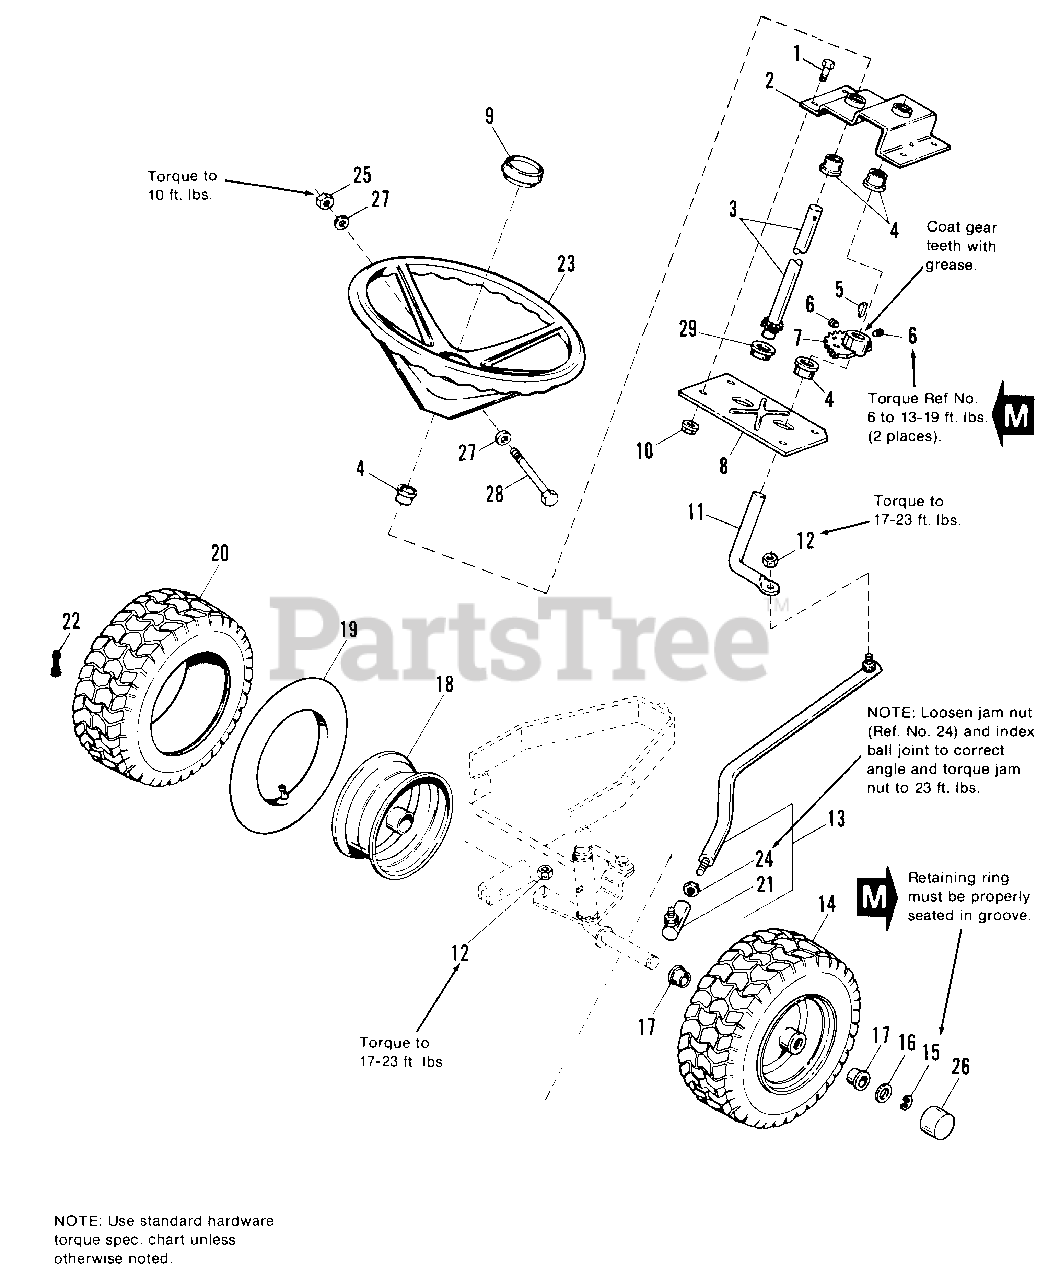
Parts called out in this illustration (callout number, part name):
1	CAPSCREW, Hex Hd., 5/16-18 x 3/4
2	PLATE, Steering
3	SHAFT ASSY., Steering
4	BUSHING, Nylon, Long
6	SETSCREW, 5/16-18 x 1/2
7	GEAR, Steering
8	PLATE, Base, Steering
9	CAP, Steering Wheel
10	LOCKNUT, Hex, Flange, 5/16-18
11	ROD, Steering
12	NUT, Special, 3/8-24
13	LINK ASSY., Drag (Incl. Ref. No. 21 & 24)
14	WHEEL & TIRE ASSY.
18	WHEEL ASSY. 15 x 6.00-6 (Incl. Ref. No. 17)
19	TUBE, 4.10/3.50-6 (For Service Only)
20	TIRE, (Carlisle) 15 x 6.00-6
21	BALL JOINT ASSY.
22	VALVE STEM & CAP
23	WHEEL, Steering, Bolt Mounted
24	NUT, Jam 3/8-24
25	LOCKNUT, Hex, 5/16-18
26	HUB CAP, Threaded
27	WASHER, Plain
28	BOLT, 5/16-18 x 3-1/2
29	BUSHING, Nylon, Short
